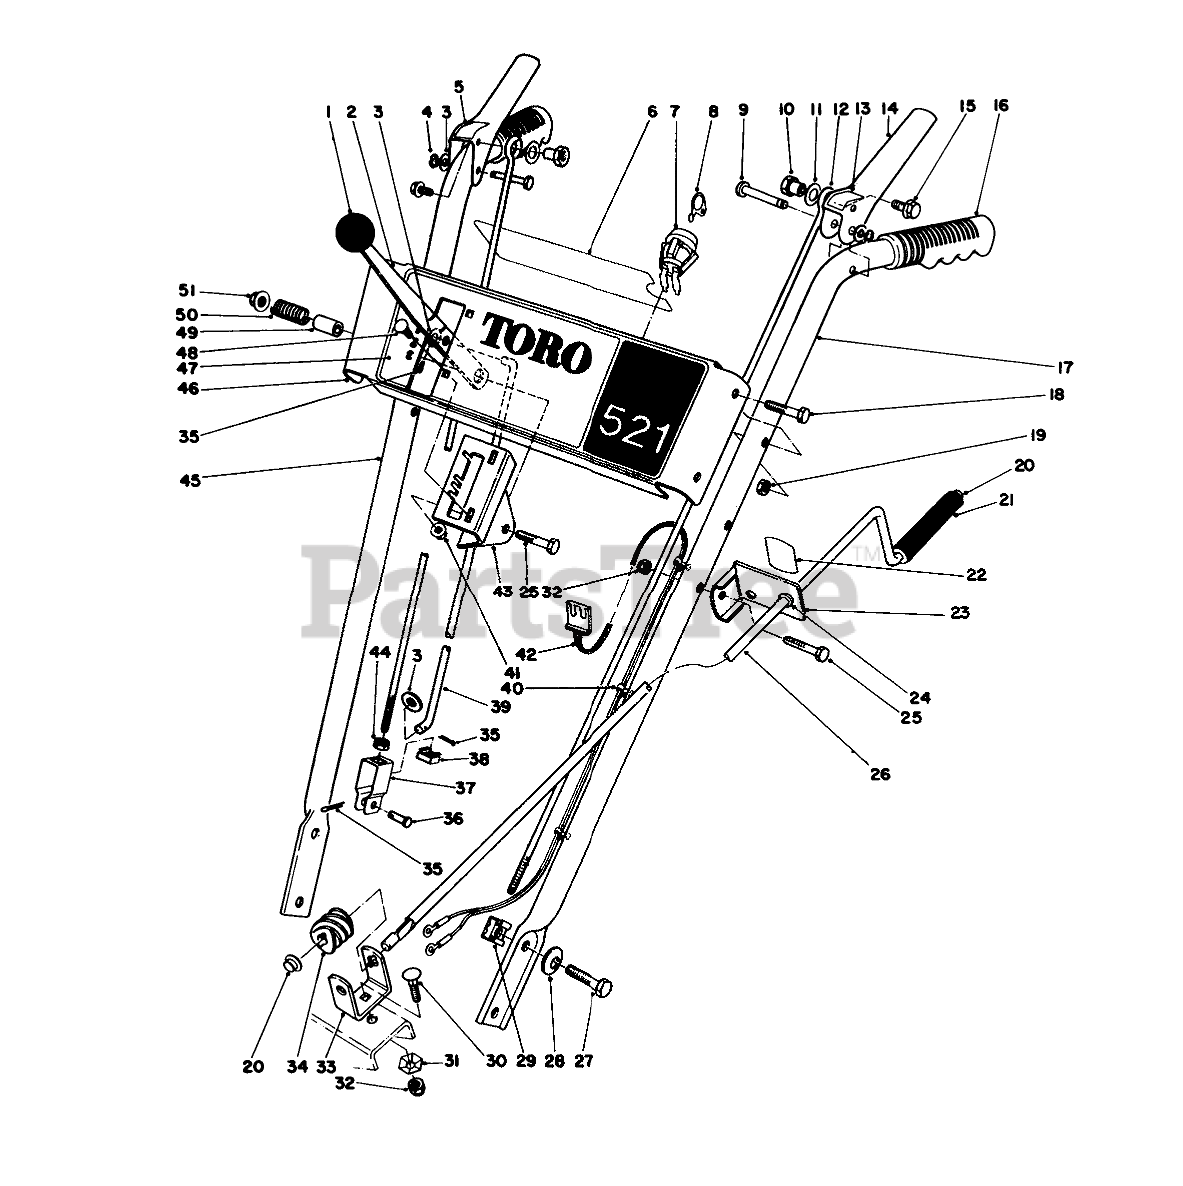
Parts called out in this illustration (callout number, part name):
2	SPEED SELECTOR B
3	WASHER-PLAIN
4	RING-CLIP
5	DECAL
6	Decal-Escutcheon Back
7	SWITCH
8	Key
9	PIN-LEVER, CONTROL
10	POST-MOUNTING, LINKAGE
11	WASHER-FLAT
12	LINK-UPPER
13	DECAL
14	Handle-Control
15	SCREW-HHF
16	Grip
17	LEFT HANDLE
18	SCREW-HH
19	NUT-LOCK, CONE
20	RETAINER-PUSH ON
21	GRIP-CONTROL, CHUTE
22	CHUTE DECAL
23	Bracket-Chute Control (Incl. Ref. #22 & 24)
24	Bushing
25	SCREW-HH
26	ROD-CONTROL, CHUTE
27	SCREW-HH
28	WASHER-BELLEVILLE
30	BOLT-CARR
31	WASHER-LOCK
32	NUT-LOCK, NI
33	BRACKET-WORM
34	GEAR-WORM, CHUTE
35	PIN-COTTER
36	PIN-CLEVIS
37	CLEVIS
38	NUT-RETAINED
39	ROD-SELECTOR, SPEED
40	Mount-Wire
41	NUT-HHF
42	Wire Harness Assembly (Incl. Ref. #40)
43	Mount-Speed Selector
44	NUT-JAM
45	RIGHT HANDLE
46	ESCUTCHEON PLT B
47	Decal-521
48	SCREW-CARRIAGE
49	SPACER
50	SPRING
51	NUT-HF
